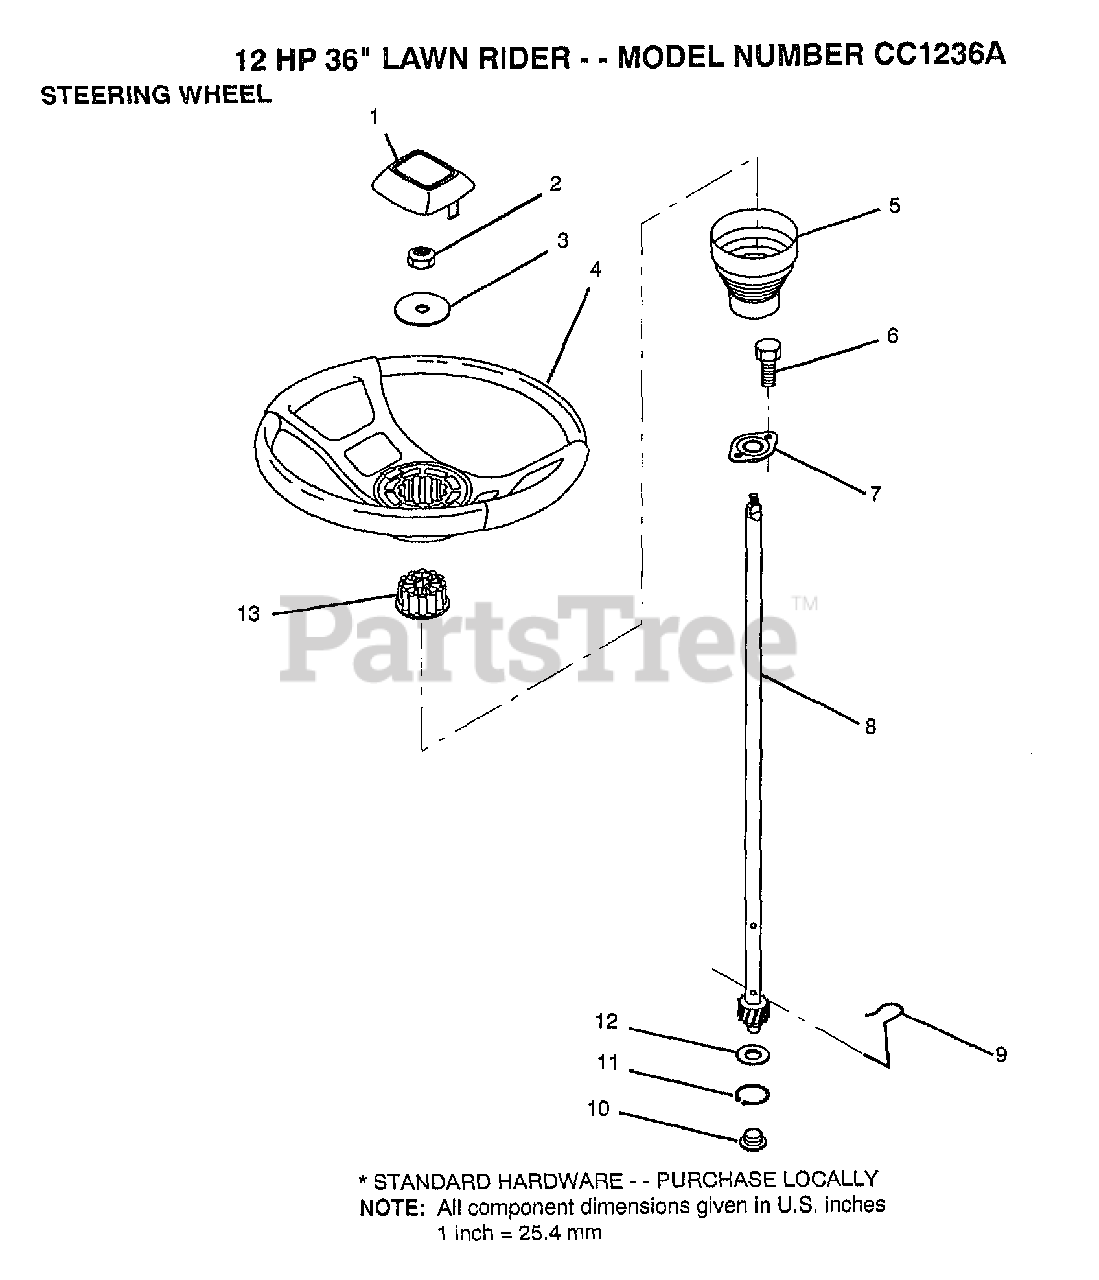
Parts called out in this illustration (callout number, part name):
1	INSERT-WHEEL LT
2	GRIPCO NUT
3	WASHER T
5	SLEEVE STEERING
9	STEERING CLIP
10	BUSHING STEER LWR
11	RING
12	WASHER LT
13	ADAPTER-WHEEL LT
